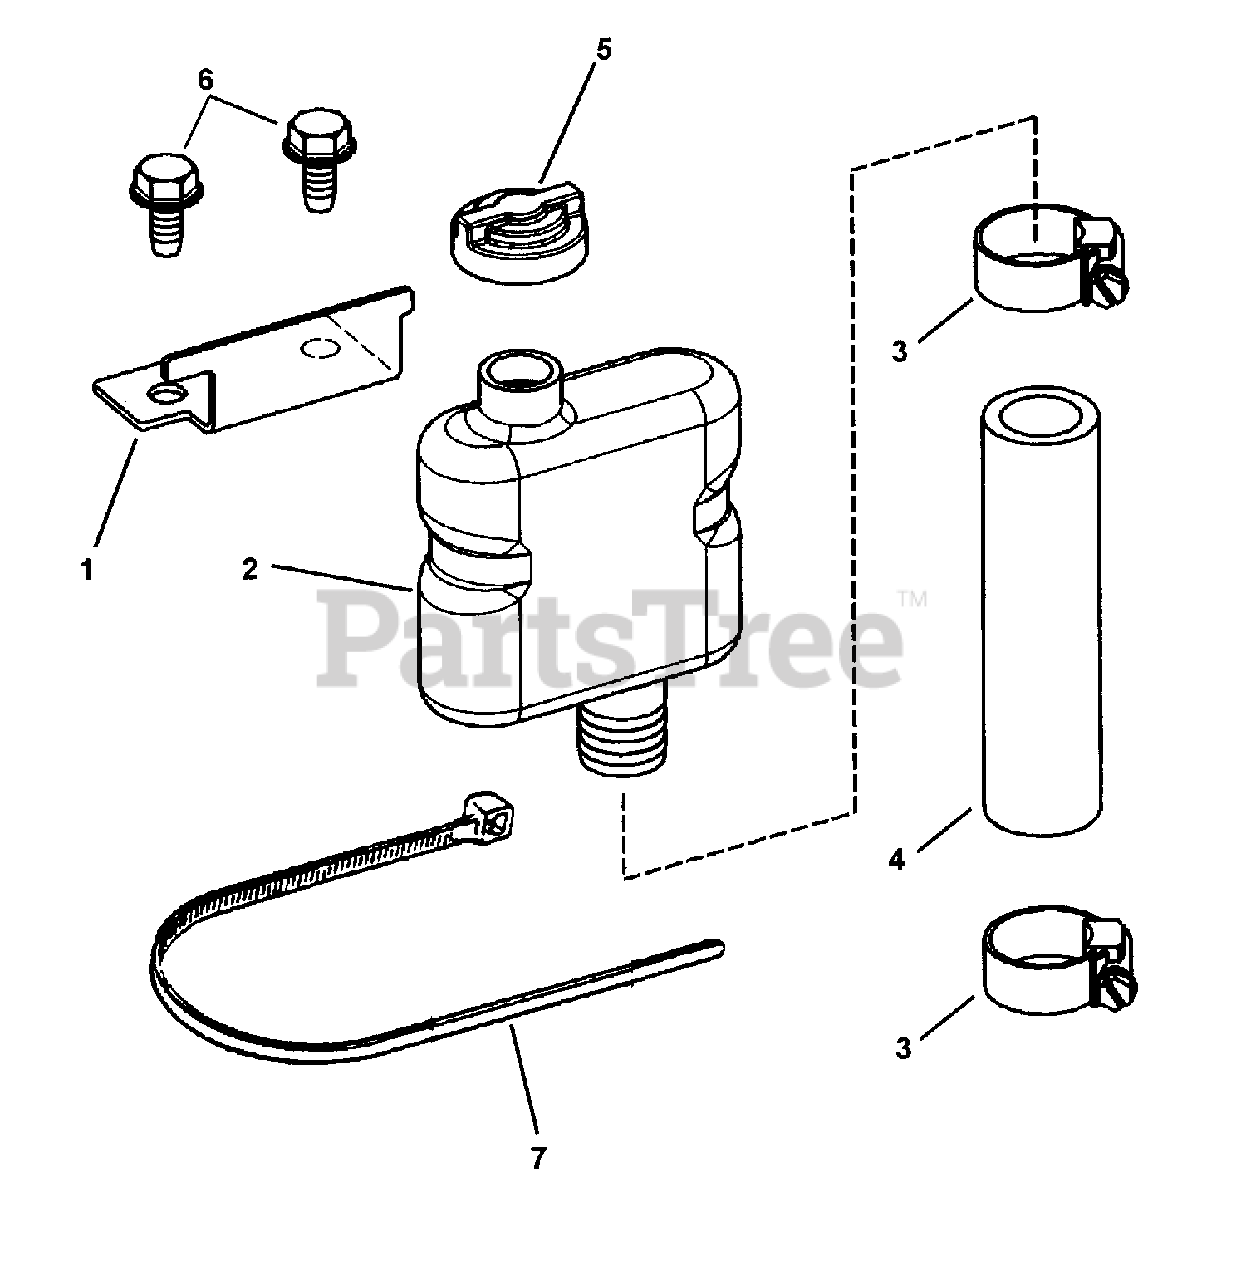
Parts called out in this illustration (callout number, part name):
1	BRACKET, Reservoir Mounting
2	RESERVOIR, Expansion- TTK46 Hydro
3	CLAMP 13/16"
4	HOSE, Hydraulic-(4-1/2" long) TTK46 Hydro
5	VALVE, Vent
6	SCREW, 5/16-18 x 1/2" Hex Washer Self-Tap
7	CABLE TIE - 10 x 1/4 x .083 thick
